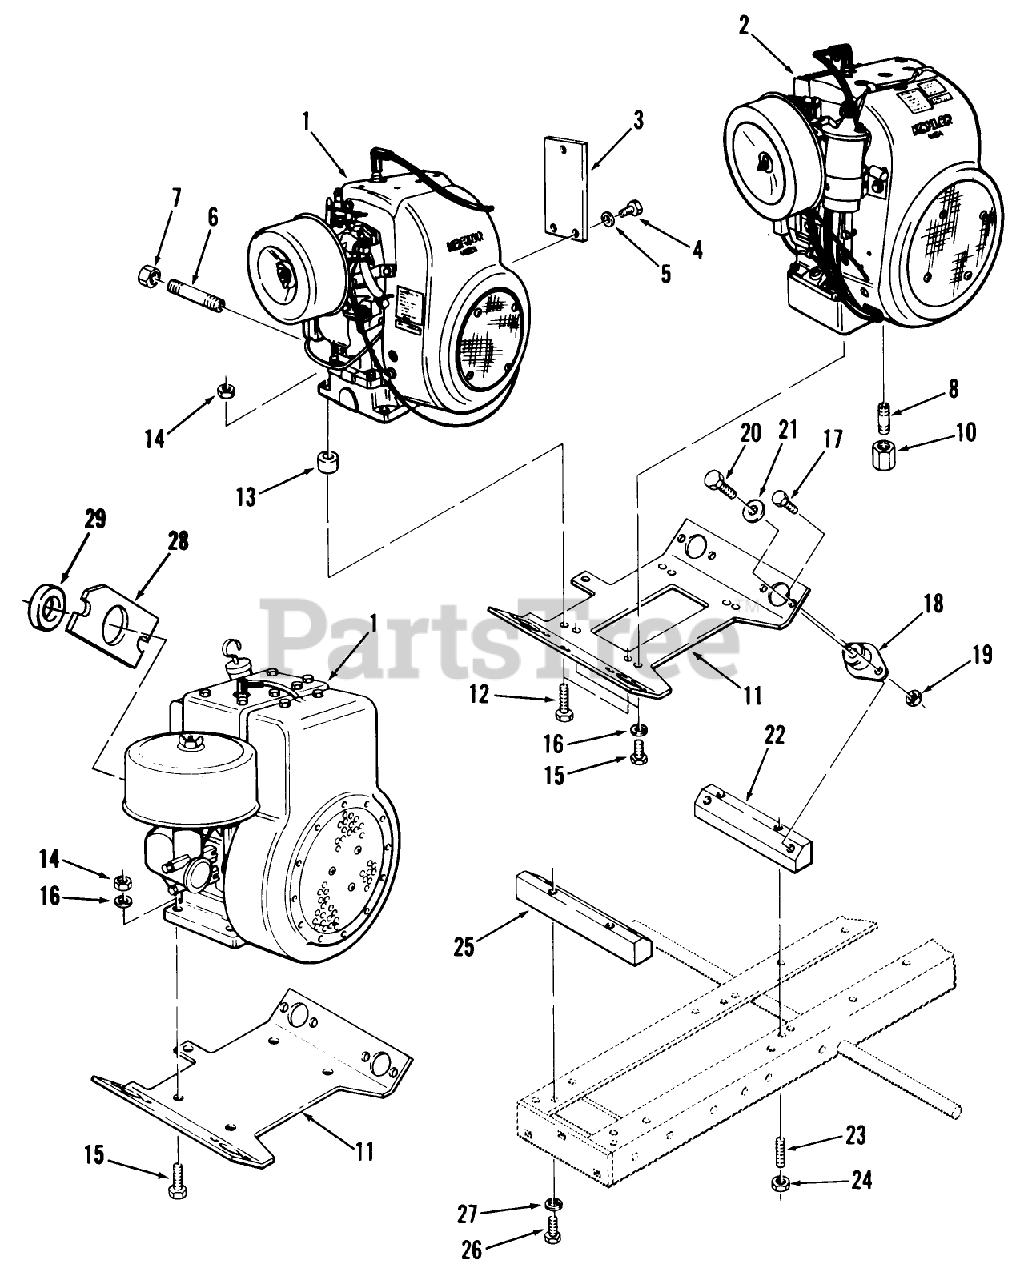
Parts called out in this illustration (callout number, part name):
1	Engine-11 HP Briggs Stratton 252417 Type 0198-01
1	Engine-8HP Kohler K-181S Spec Pf-30700D
2	Engine-12HP Kohler K-301AS Spec Pf-47648D
2	Engine-14HP Kohler K-321AS Spec Pf-60322D
2	Engine-16HP Kohler K-341AS Spec Pf-71246A
2	Engine-10HP KohlerK-241AS Spec Pf-46766D
29	Thrust Bearing C-111 Only
